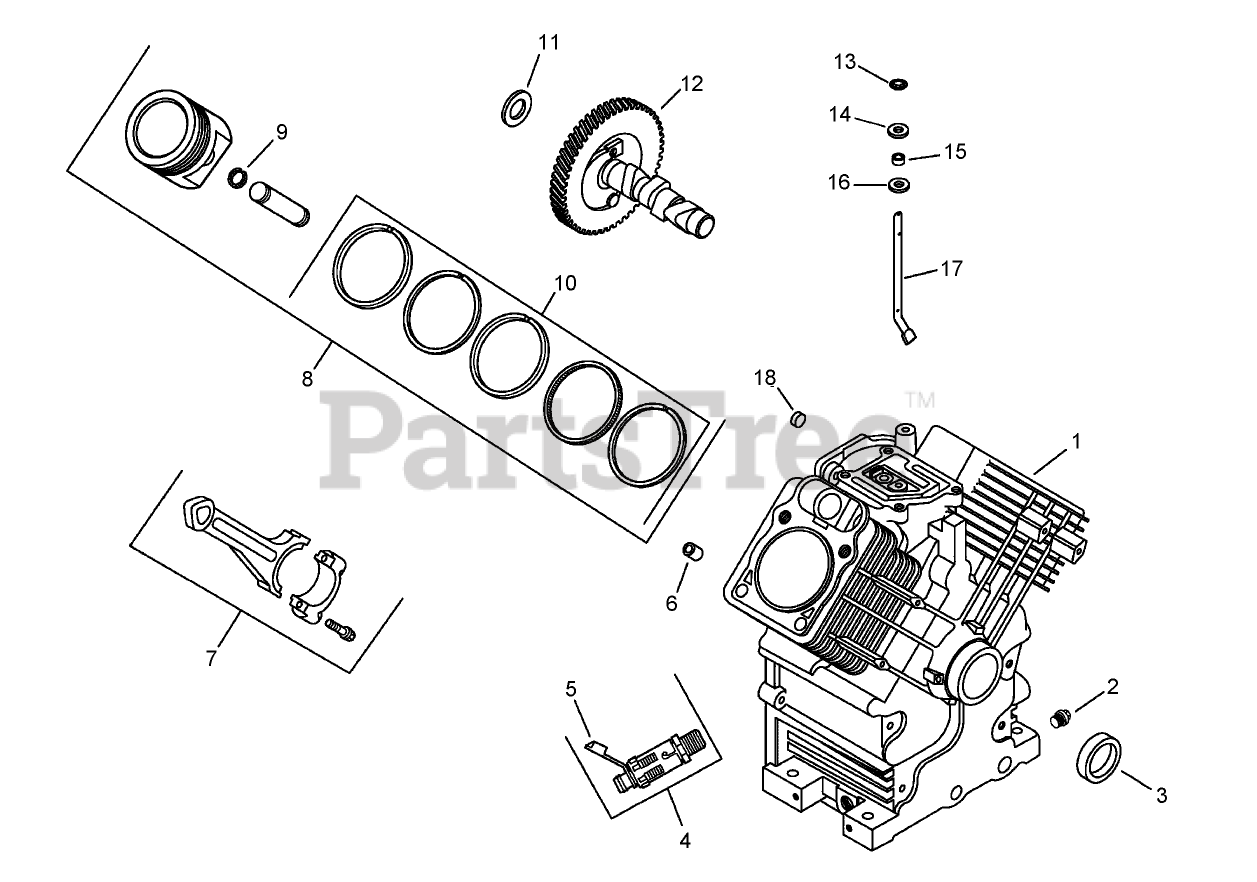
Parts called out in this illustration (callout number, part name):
1	Crankcase
2	PLUG-PIPE HEAD, 3/8
3	SEAL-OIL
4	Valve-Drain, Oil (Includes 5)
5	CAP-VALVE, OIL DRAIN
6	PIN-LOCATING
7	Rod-Connecting (Standard)
8	Piston w/Ring Set (STD) (Includes 9,10)
9	RETAINER-PIN, PISTON
10	Ring Set (.25)
11	SHIM-CAMSHAFT (RED .032)
12	CAMSHAFT KIT
13	RETAINER-RING
14	WASHER-FLAT (9MM)
15	SEAL-CROSS SHAFT, GOVERNOR
16	WASHER-FLAT (11/32)
17	SHAFT-CROSS, GOVERNOR
18	PLUG-CUP
